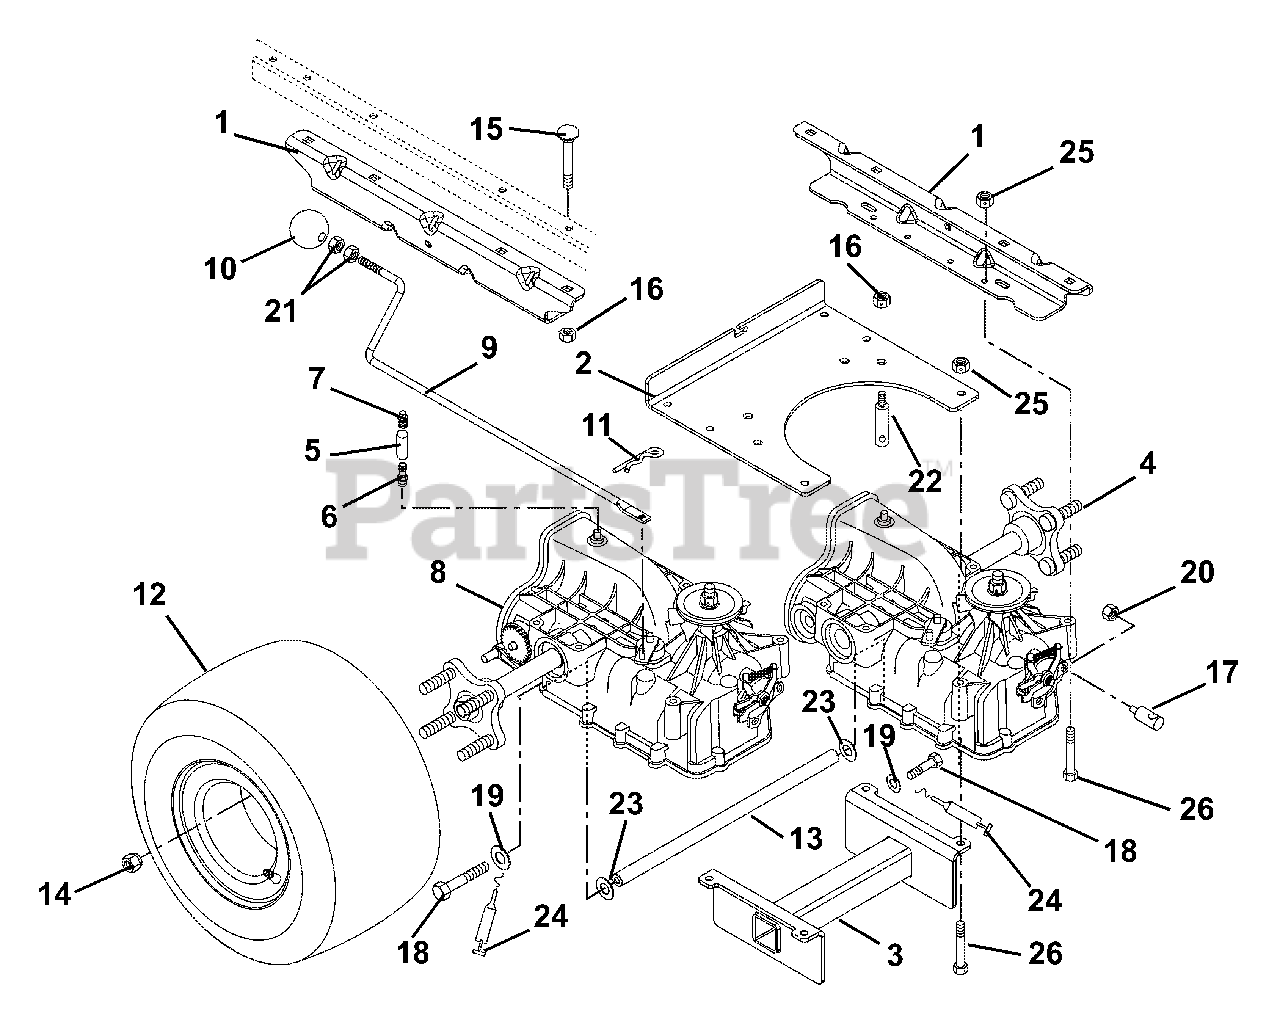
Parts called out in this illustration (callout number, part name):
1	Bracket, Transmission Axle
2	Bracket, Transmission Axle Support
3	Weldment, Transmission Axle Brace
4	Transaxle, Left Hand
5	Hose, Vent
6	Fitting, Straight .50 O-Ring Hydro-Gear
7	Cap, Vent .50 Hydro-Gear
8	Transaxle, Right Hand
9	Rod, Dump IZT
11	Pin, Hair
12	Assembly, Tire 9.5 x 18-2 Ply (046, 048, 050)
12	Assembly, Tire 8.5 x 18 2 Ply (044)
13	Rod, Axle Brace
14	Nut, Lug .50-20
15	Bolt, Round Head Square Neck .38-16 x 2.25 Grade 5
16	Nut, .38-16 Flange Nyloc
17	Rod Pivot
18	Bolt, Hex .31-18 x 2.50 Grade 5
19	Washer, Locking .31 x .078 Regular
20	Nut .312-18 Flange Nyloc
21	Nut, Jam .312-18
22	Shoulder Stud
23	Washer, Flat Steel .38 x .87 x .179
24	Adhesive Sealant
25	Nut-.31-18 Flange Nyloc
26	Bolt-Hex .31-18 x 2.75 Grade 5
